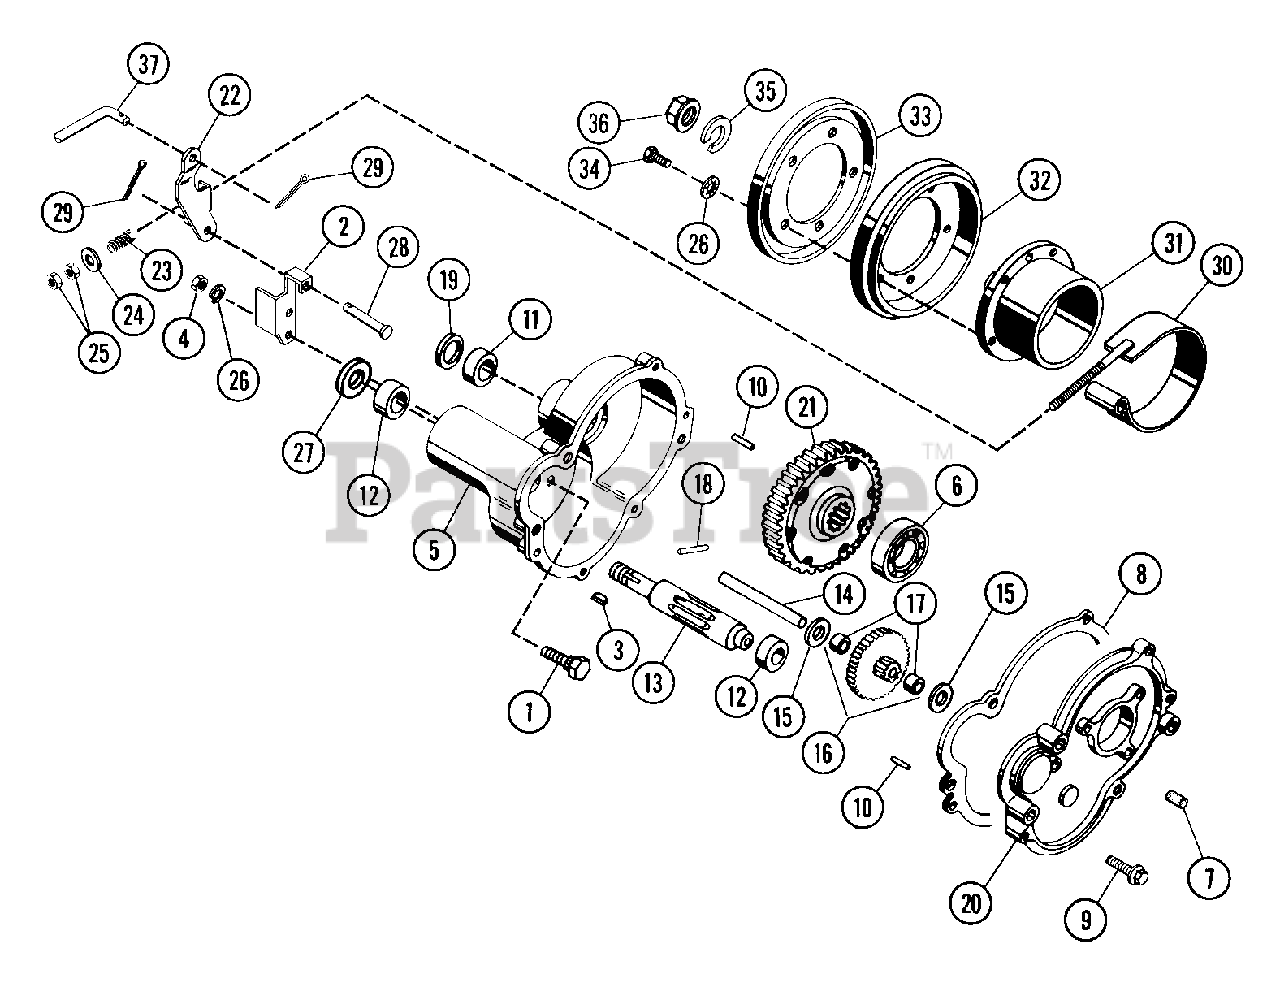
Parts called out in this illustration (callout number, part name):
1	BLT-SERRDHD SL .31-18X.75 YZ
2	BRAKE BRACKET
3	KEY-WDRF .188X.875X.375 SAE11
4	NUT-HEAVY .312-18 PL
5	SERVICE GEAR CASE
6	BRG-BALL 1.125X2.50X.63
7	BREATHER
8	GASKET
9	SCR-FLG-WHZ 10-24X.75 PL
10	PIN-GRV .188X.63
11	BSHG-SLV .875X1.125X1.046
12	BRG-BALL .625X1.375X.44
13	PINION SHAFT
14	IDLER SHAFT
15	WSHR-FL-STL .505X.875X.024 PL
16	PINION & GEAR W/BEARING ASSEMB
17	BRG-NEEDLE .50X.688X.625
18	PIN-ROLL .125X.75
19	SEAL .875X1.125X.125
20	GEAR CASE COVER ASSEMBLY
21	DIFFERENTIAL ASSEMBLY
22	BRAKE LEVER
23	SG-COMP .105X.585X.75
24	WSHR-FL-STL .323X.625X.062 PL
25	NUT-HEX .312-18
26	WSHR-LK-INT .313X.030 PL
27	WSHR-FL-STL .627X.990X.032
28	PIN-CLEV .371X3.25
29	PIN-COTR .09X.75 PL
30	BRAKE BAND
31	FRICTION DISC HUB
32	FRICTION DISC
34	BLT-HEX .31-18X.50 PL GR2
35	WSHR-LK-INT .625X.045 PL
36	NUT-LK-NYL.625-18 PL
37	BRAKE ROD
